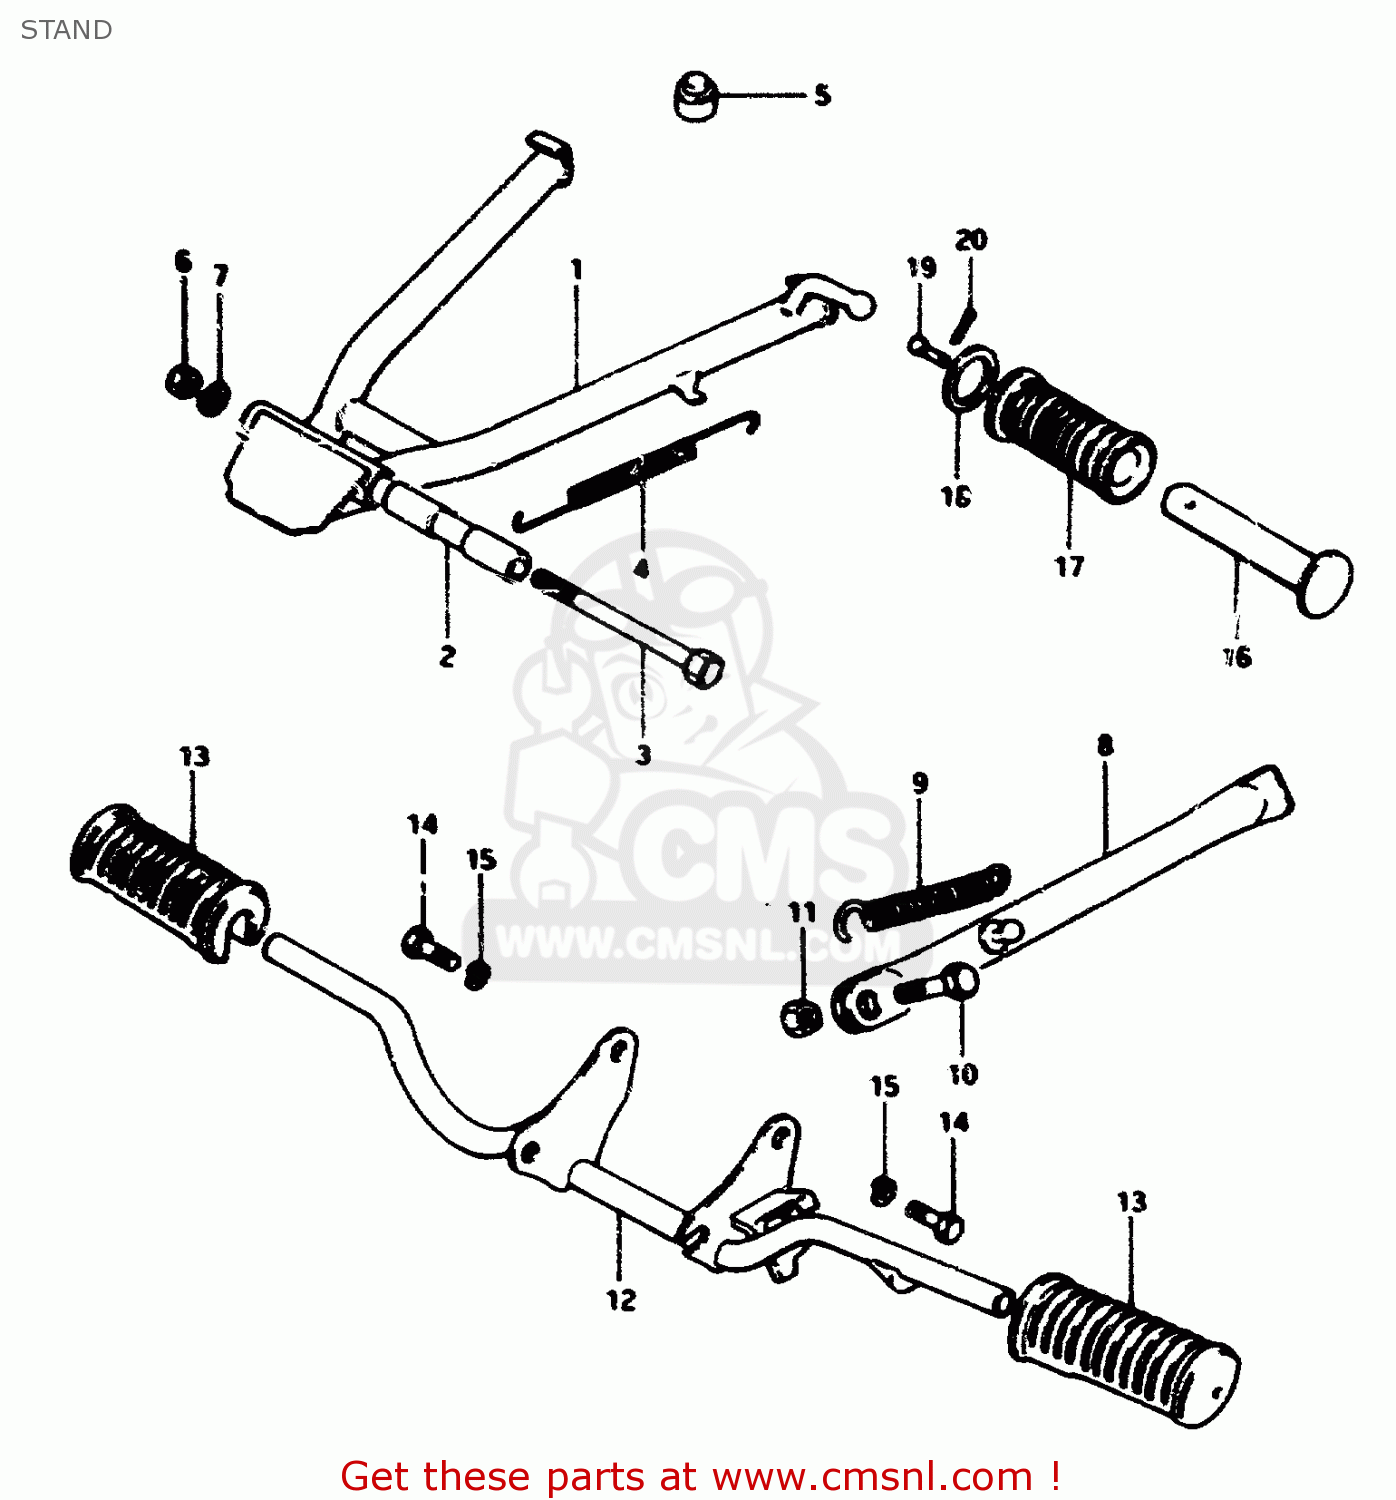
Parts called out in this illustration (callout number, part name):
1	STAND, CENTER
2	SPACER
3	BOLT(10X110)
4	SPRING
5	CUSHION
6	NUT
7	LOCK WASHER
8	STAND, PROP
9	SPRING
10	BOLT
11	NUT
12	BAR,FRONT FOOTREST
13	RUBBER,FR FOOTREST
14	BOLT
15	LOCK WASHER
16	BAR,FOOTREST RUBBER
17	RUBBER,PILLION FOOTREST
18	WASHER (19.5X32X2)
19	PIN
20	PIN 20X20
